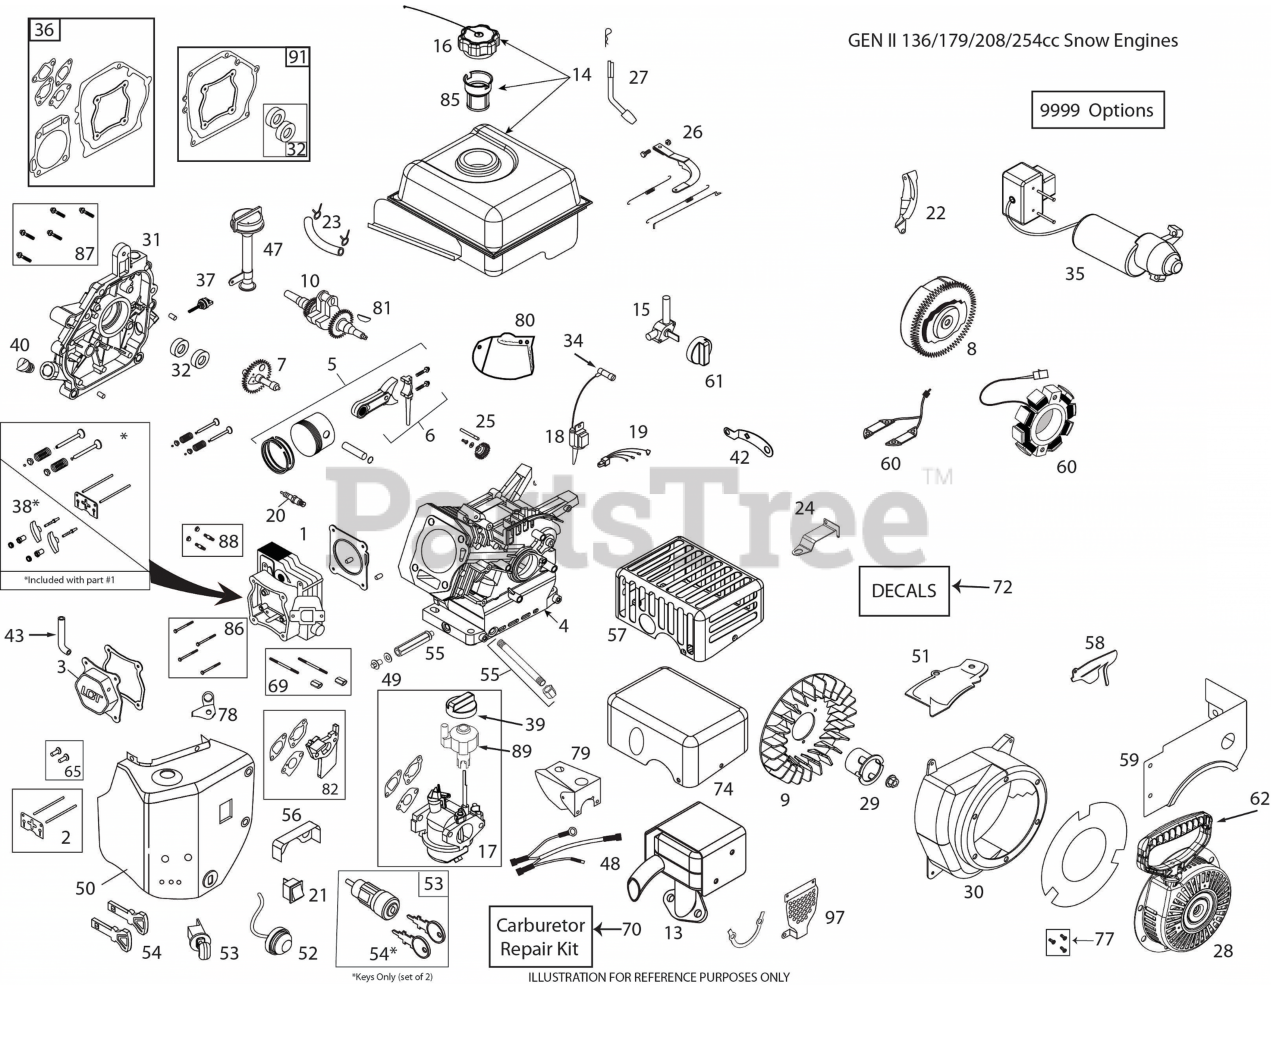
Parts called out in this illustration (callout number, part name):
2	PUSH ROD & PLATE KIT (W/GASKT)
3	VALVE COVER (W/GASKET )
7	CAMSHAFT - MCR
8	FLYWHEEL - ELECTRIC START
9	COOLING FAN - FLYWHEEL
13	MUFFLER ASSEMBLY
14	FUEL TANK ASSY
15	FUEL TANK ON/OFF VALVE
16	CAP, FUEL TANK BLACK
18	IGNITION COIL (CDI) (HI-TEMP)
20	SPARK PLUG, ARIENS AX
22	SHIELD - FLYWHEEL
23	FUEL HOSE KIT 1/4-318MM
24	SPEED CONTROL BRACKET (FIXED)
25	GOVERNOR GEAR ASSEMBLY
26	GOVERNOR ARM & LNK KIT 3600RPM
27	GOVERNOR ARM PADDLE
28	RECOIL STARTER ASSY RND-BLACK
29	STARTER CUP RND STYLE STARTER
32	OIL SEAL KIT(2 PCS 3/4" CRANK)
34	SPARK PLUG BOOT (W/MTL SHIELD)
35	120V ELECT START CONVERSON KIT
37	SMALL BLACK OIL DIPSTICK
38	ROCKER ARM KIT (W/GASKET)
39	CHOKE CONTROL KNOB (RED)
43	BREATHER TUBE
48	WIRE HARNESS
49	OIL DRAIN PLUG (W/WASHER)
50	HEATER BOX KIT
51	SHIELD - CYLINDER
52	PRIMER BULB WITH HOSE-SNOW (RED)
53	SAFETY KEY SWITCH (W/KEYS) (RED)
54	KEY, PUSH/PULL LCT (2/PACKAGE)
55	FRONT OIL DRN PIPE & NUT ASSY
57	CE COMPLIANT MUFFLER SHIELD
58	SHIELD - GOVERNOR LINKAGE
59	FUEL TANK SKIRT
61	FUEL CONTROL KNOB (RED)
62	STARTER GRIP
65	TAPPET KIT (SET OF 2)
69	CARBURETOR STUDS & COUPLNG KIT
70	CARBURETOR REPAIR KIT
72	LABEL KIT (EFI)
74	MUFFLER HEAT SHIELD COVER
77	RECOIL BOLT KIT
78	BREATHER TUBE BRACKET
81	WOODRUFF FLYWHEEL KEY 5-PACK
82	CARBURETOR SPACER
85	FUEL TANK STRAINER
86	HEAD BLT KIT 136-179-208-254CC
87	CC COVER BLT KIT 179-208-254CC
88	MUFFLER MTG STUD KIT
91	CRANKCASE GASKET KIT 208GEN1&2
97	Muffler Manifold Guard
9999	HIGH ALT JET-208CC L10-1 CARB
9999	HARDWARE KIT (4 M6X10 FLG BLT)
9999	STARTER SWITCH SCREWS
9999	M6X30 ELEC STARTER MNTG BOLTS
9999	CLIPS, CARB THROTTLE LINKAGE
9999	BOTTLE 16 OZ 5W-30 OIL
